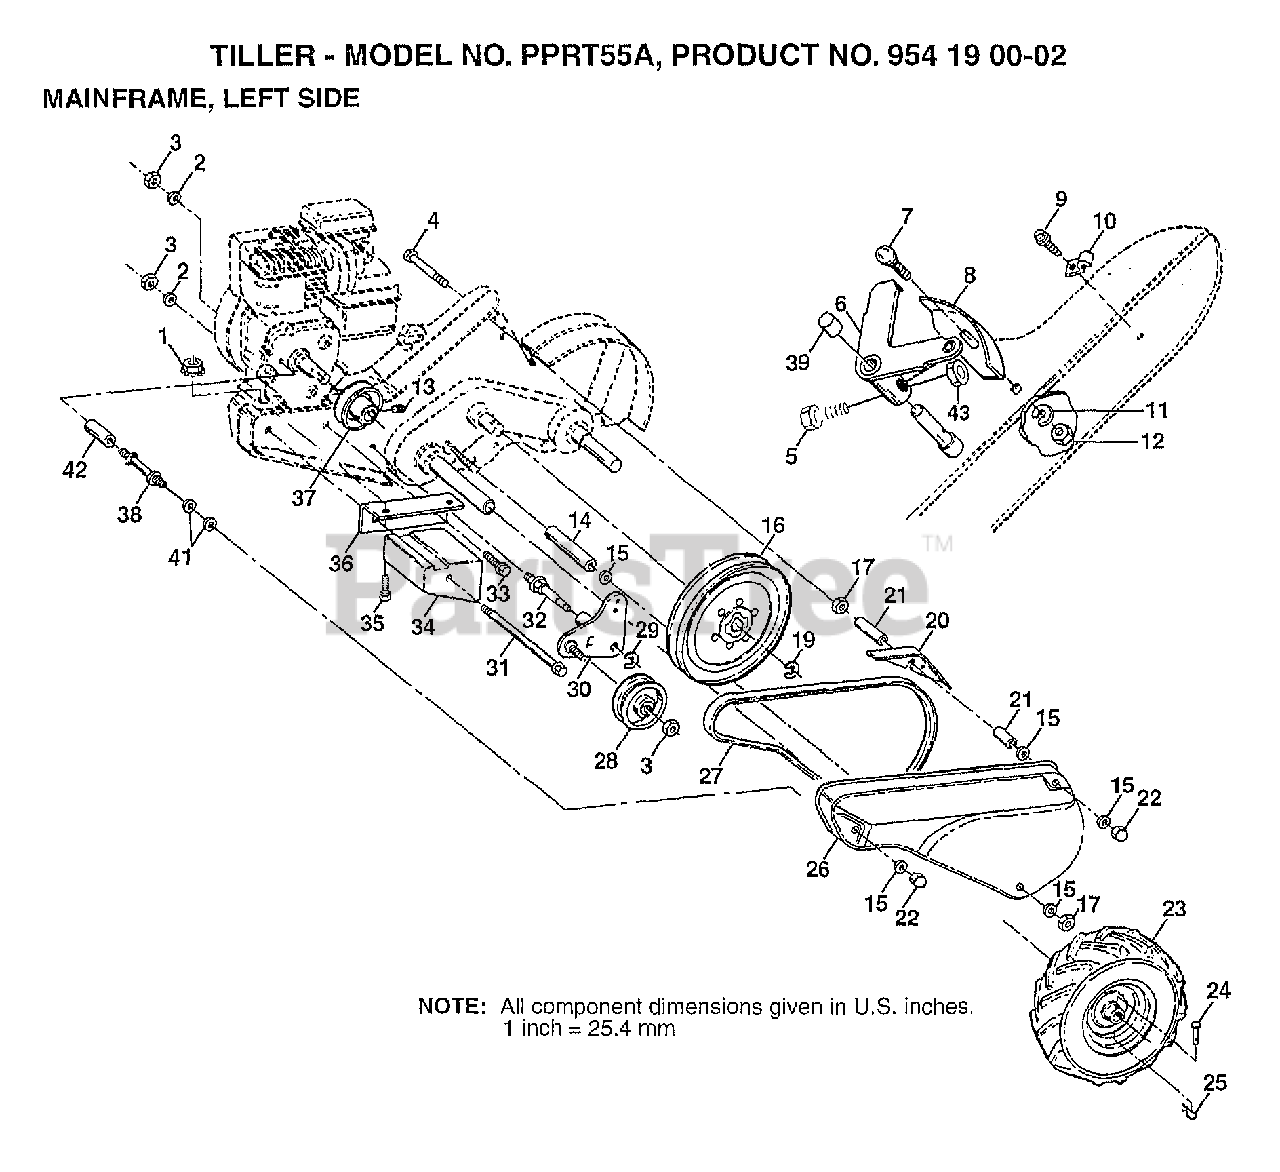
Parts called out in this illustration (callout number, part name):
2	LOCKWASHER
3	NUT.HEX.3/8-16UNC
4	BOLT TI
5	"SCREW-LEVER,SHI"
6	LEVER SHIFT
7	BOLT
8	PANEL TI
10	CONDIUT CLIP T
11	LOCKWASHER
13	SET SCREW
14	SPACER, SPLIT
15	WASHER
16	SHEAVE, TRANSMISSION
17	NUT.HEX.5/16-18
20	GUARD, PINCH POINT
21	SPACER SPLIT
23	TIRE TI
24	RIVET DRILLED
27	BELT-V
28	PULLEY, IDLER
29	KLIP RING
30	BRACKET, IDLER
32	SHAFT, IDLER ARM
33	BOLT
34	COUNTERWEIGHT
35	BOLT
36	BRACKET, REINFORCEMENT
37	ENGINE PULLEY
38	STUD.GUARD.BELT
39	CAP PLUNGER BLACK
41	WASHER
43	LOCKNUT
